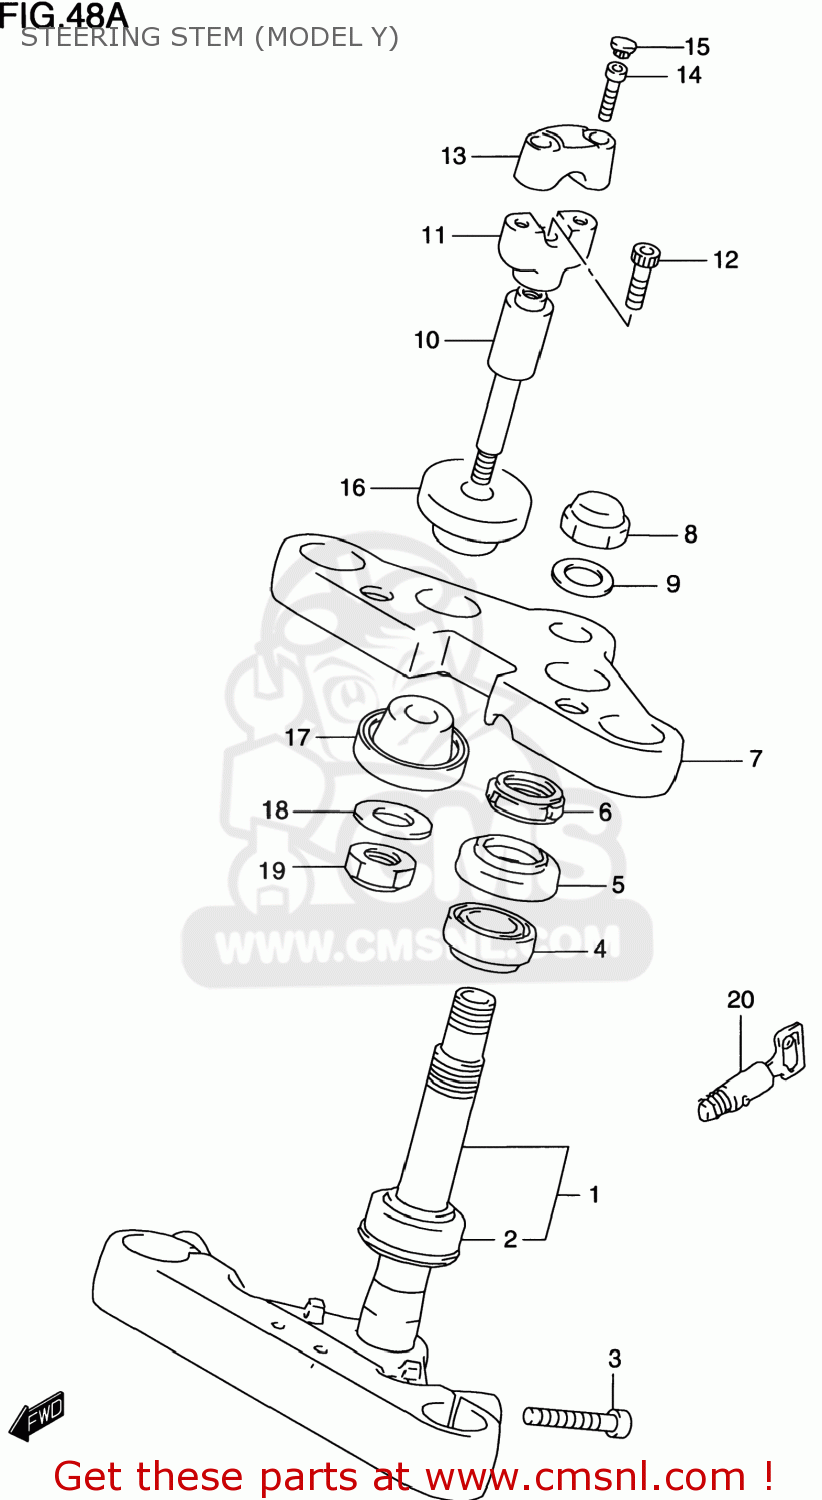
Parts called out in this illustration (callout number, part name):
1	STEM,STEERING
2	BEARING(30X55X17)
3	BOLT
4	BEARING(25X47X15)
5	SEAL,STEERING UPR DUST
6	NUT,STEERING STEM(25X44X10)
7	BRACKET,UPR
8	NUT,CAP
9	WASHER(22.5X32X1.6)
10	STAY,HANDLE
11	HOLDER,HANDLE LWR
12	BOLT
13	HOLDER,HANDLE UPR
14	BOLT
15	CAP(OD:14.5)
16	DAMPER,RUBBER
17	CUSHION,RUBBER UNDER
18	WASHER
19	NUT
20	LOCK SET,STEERING
